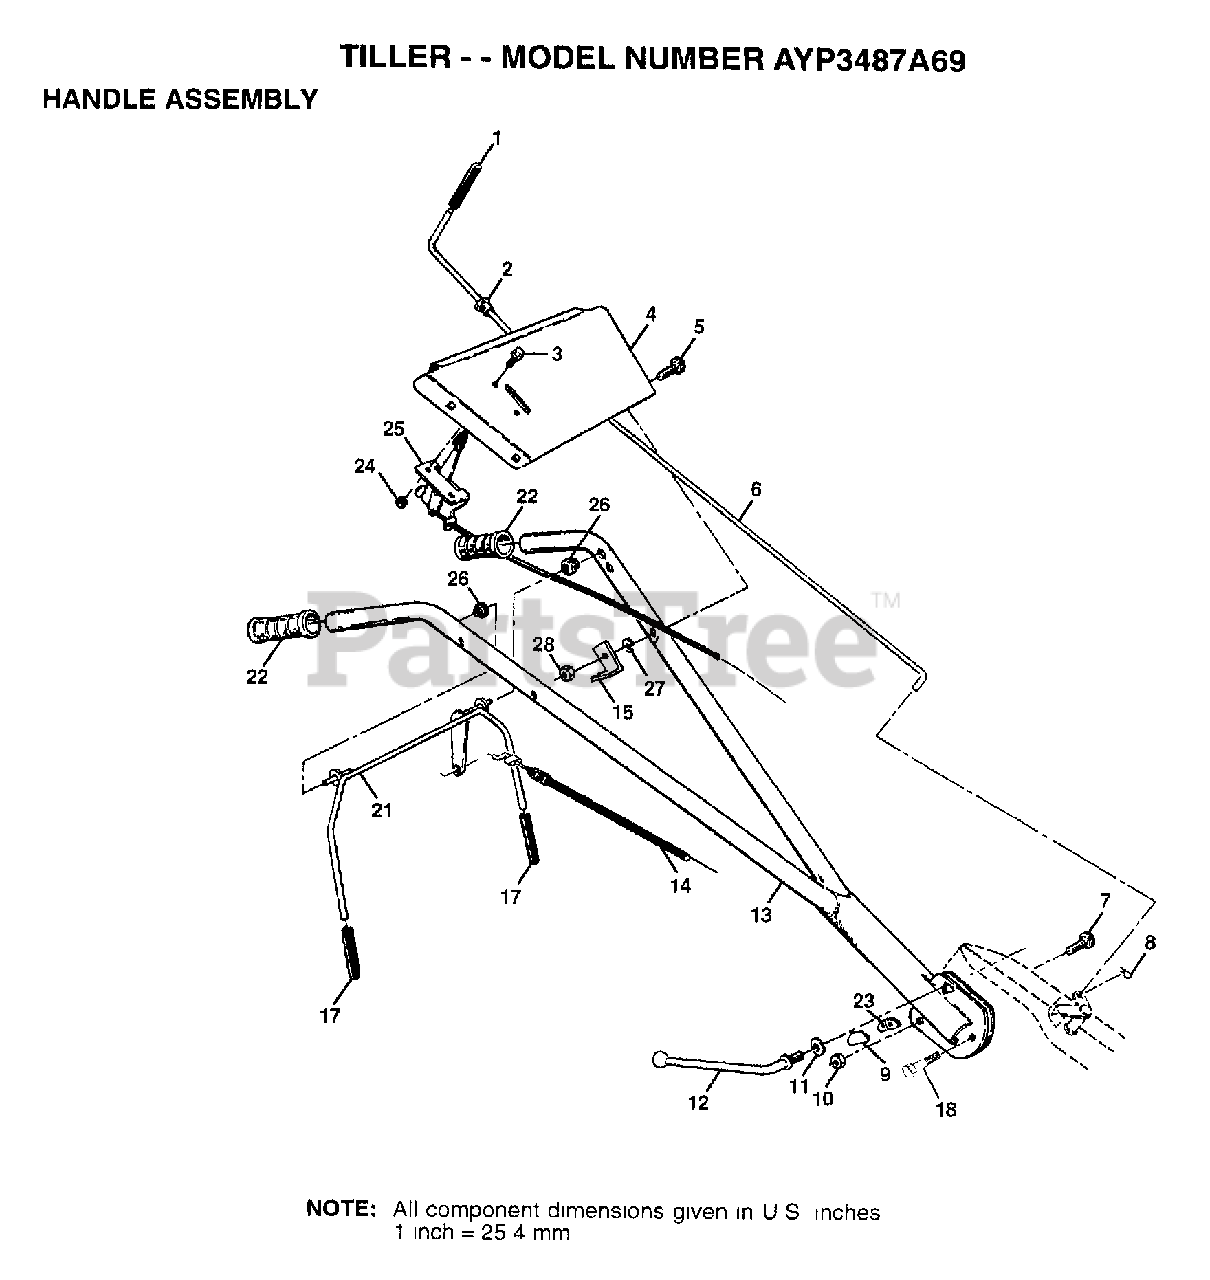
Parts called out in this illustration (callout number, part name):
1	GRIP TI
2	BUSHING
3	SCREW.PNHD.10-24
4	HANDLE BRACKET
5	BOLT CARRIAGE CRT
6	ROD SHIFT CRT
7	BOLT D
8	RETAINER M
9	LOCK CRT
10	LOCKNUT
11	WASHER CRT
12	LEVER LOCK CRT
14	CABLE.CLUTCH.Z-BE
15	BRACKET.CLUTCH.CA
17	GRIP BAR CRT
18	BOLT PIVOT
21	BAR.ASM.CNTRL.VPL
22	"GRIP,HANDLE"
23	LOCK.HANDLE
25	"CONT,THROTTLE"
26	GROMMET.HANDLE.V-
27	LOCKWASHER
28	NUT
